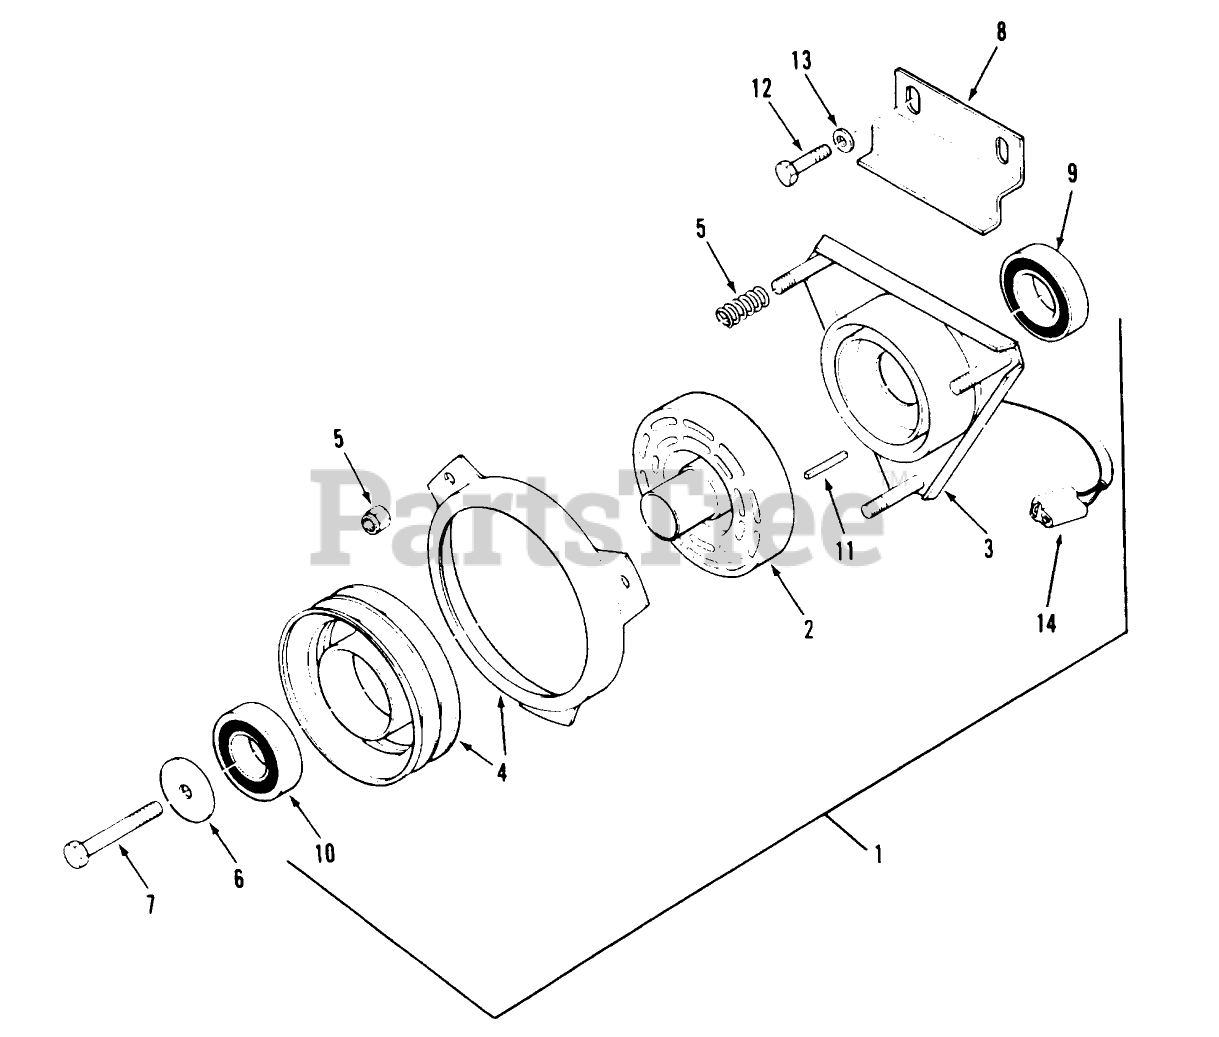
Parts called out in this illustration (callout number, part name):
1	Electric Clutch-Complete (Incl. Ref. #2, 3, 4, 5, 9, 10, & 14)
2	Rotor & Armature Asm (Incl. Ref. #4 & 10)
3	Field (Incl. Ref. #9)
5	ACCESS SPRING & NUT
6	RETAINER-BEARING
7	SCREW-HH
8	BRACKET-CLUTCH B
9	BEARING-FIELD ASS'Y
10	BEARING-ELEC CLUTCH
11	KEY-SQUARE
12	SCREW-HH
13	WASHER-FLAT
14	CONNECTOR BODY B
